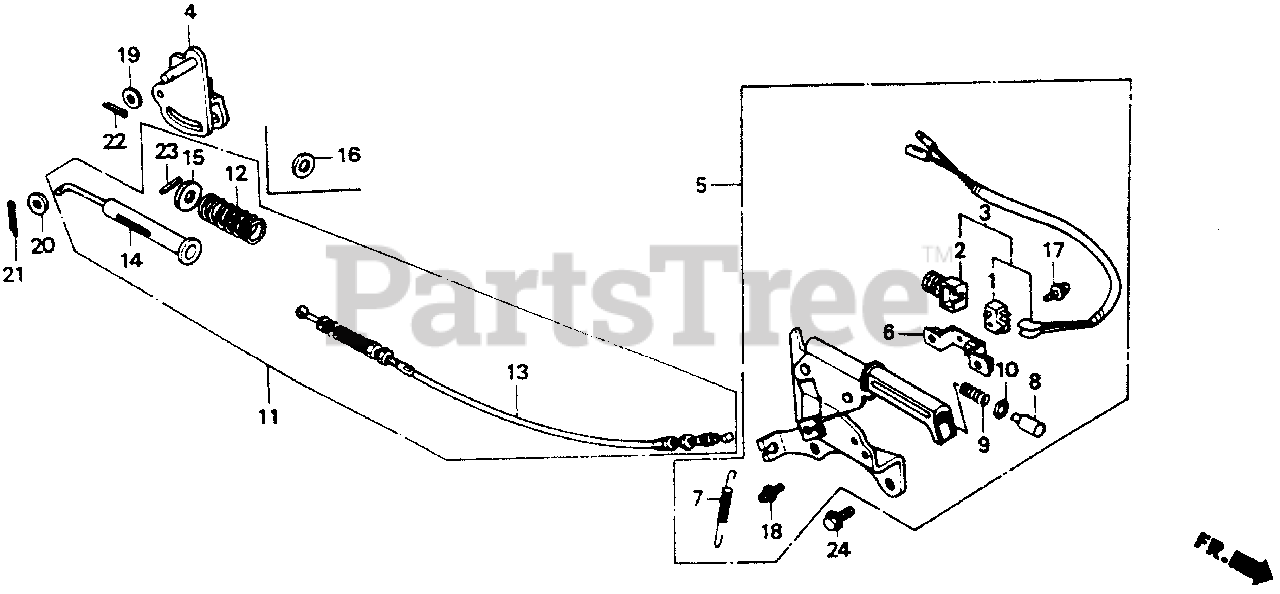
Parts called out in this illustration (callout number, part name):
2	COVER, SWITCH
3	SWITCH ASSY., PARKING BRAKE
4	ARM, BRAKE (NOT AVAILABLE)
5	LEVER ASSY., PARKING BRAKE
6	STAY, PARKING BRAKE SWITCH
7	SPRING, BRAKE LEVER RETURN
8	KNOB, PARKING BRAKE PUSH ROD
9	SPRING, PUSH ROD
10	O-RING, PARKING BRAKE LEVER
12	SPRING, PARKING BRAKE LOAD SETTING
13	CABLE, PARKING BRAKE
14	PIPE, RR. BRAKE
16	WASHER, PLAIN (17.2MM)
17	SCREW-WASHER (4X14)
18	SCREW-WASHER (5X12)
19	WASHER, PLAIN (10MM)
20	WASHER, PLAIN (5MM)
21	PIN, SPLIT (2.0X15)
22	PIN, SPLIT (2.5X30)
23	PIN, SPRING (6X25)
24	BOLT, FLANGE (8X16)
